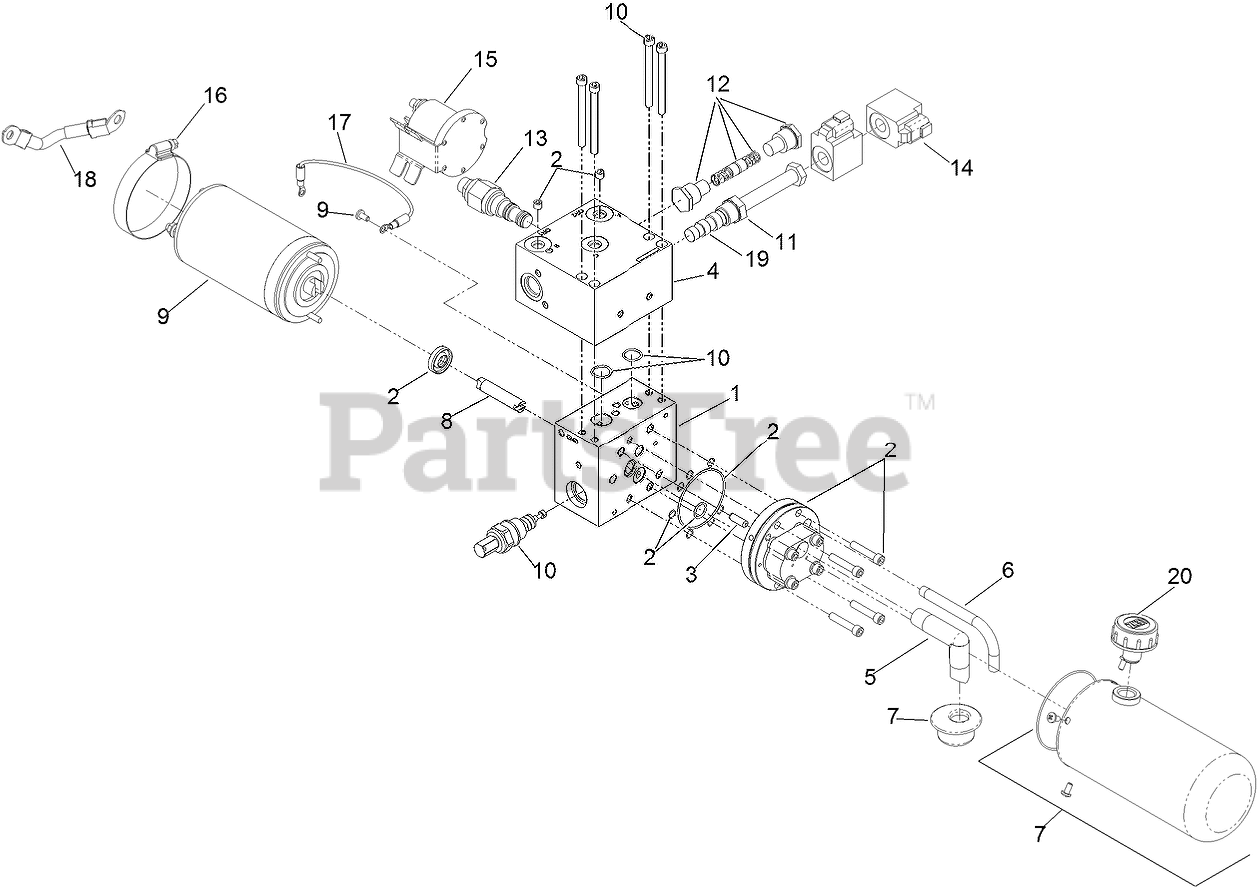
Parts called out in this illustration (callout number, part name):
1	Base Assy, M3298, 3.0 Mtr
2	P Assy,Kit,I,M3298,-100
3	Pin, Dowel, 1/4 X 3/4
4	Valve,Relief,Vm01,210-320 Bar
5	Inlet Tube,Bu
6	Tube, Return, 90DEG, 1/8NPTF
7	Parts Kit,Resv,Stl,3.375 X 7.0
8	Shaft, Intermediate, Micro, DC
9	Motor, DC, 12V, 3In, 1 Term
10	Parts Kit,Manifold Assy,M3200
11	Cartridge, 4W/3P, 3000PSI, Mc, #8
12	PARTS KIT,DBL PO CK VLV,4INMAN
13	COUNTERBALANCE, 08, 5000-PSI
14	Coil, 12Vdc, 16W, Rect, Deutsch
15	POWER UNIT SOLENOID KIT,ATV/MS-UTV
16	Clamp,Hose,Worm GR,2.3-3.25
17	Wire Assy, Cntrl, 16Awg, Hs, Ring
18	Cable, Insulated, W/Lugs, 5In, 6GA
19	Parts Kit, Seal, 4W/3P Valve
20	CAP-POWERUNIT
99	RUBY TRAN-1 GAL
